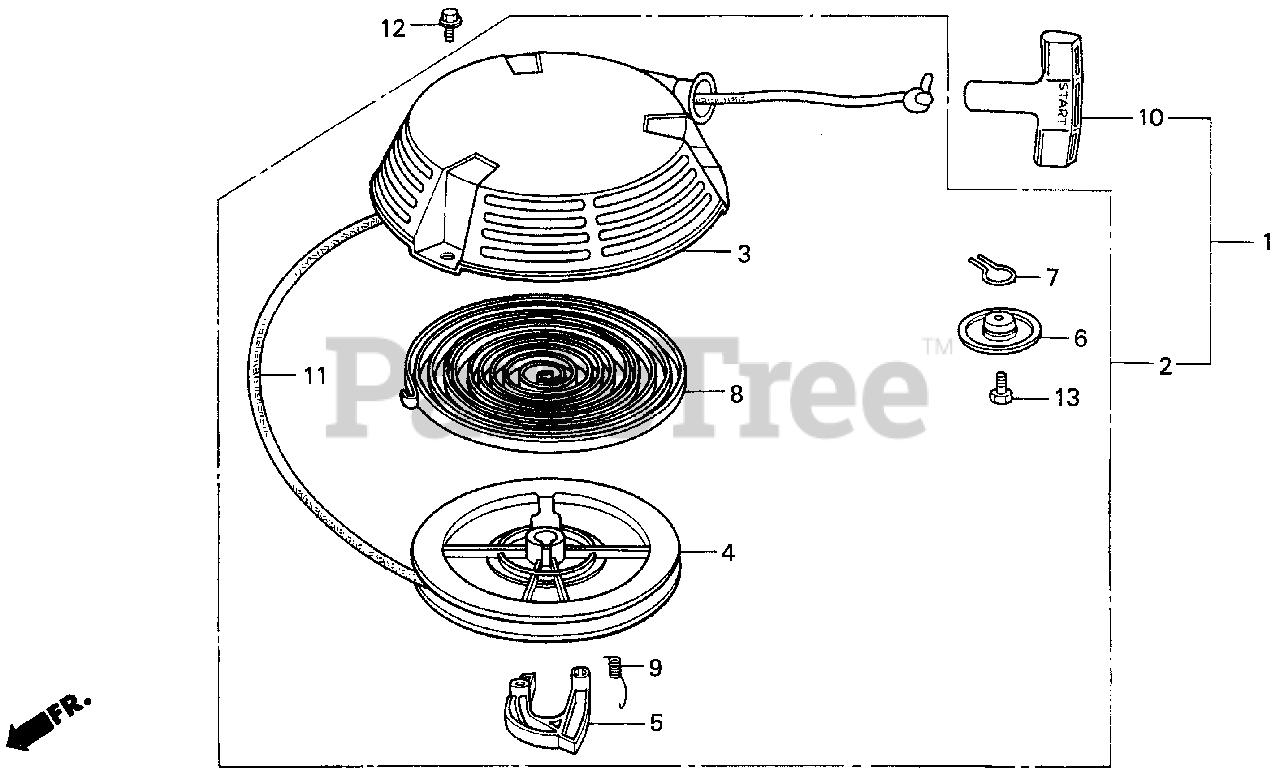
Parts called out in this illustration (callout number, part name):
1	STARTER ASSY., RECOIL *R8* (BRIGHT RED)
1	STARTER ASSY., RECOIL *R280* (POWER RED)
3	CASE, RECOIL STARTER *R8* (BRIGHT RED)
3	CASE, RECOIL STARTER *R280* (POWER RED)
4	PULLEY, RECOIL STARTER
5	RATCHET, STARTER
6	PLATE, FRICTION
7	SPRING, FRICTION
8	SPRING, RECOIL STARTER
9	SPRING, RETURN
10	KNOB, RECOIL STARTER
11	ROPE, RECOIL STARTER
11	ROPE (#4X55")
12	BOLT, FLANGE (6X8)
13	BOLT, HEX. (6X12)
